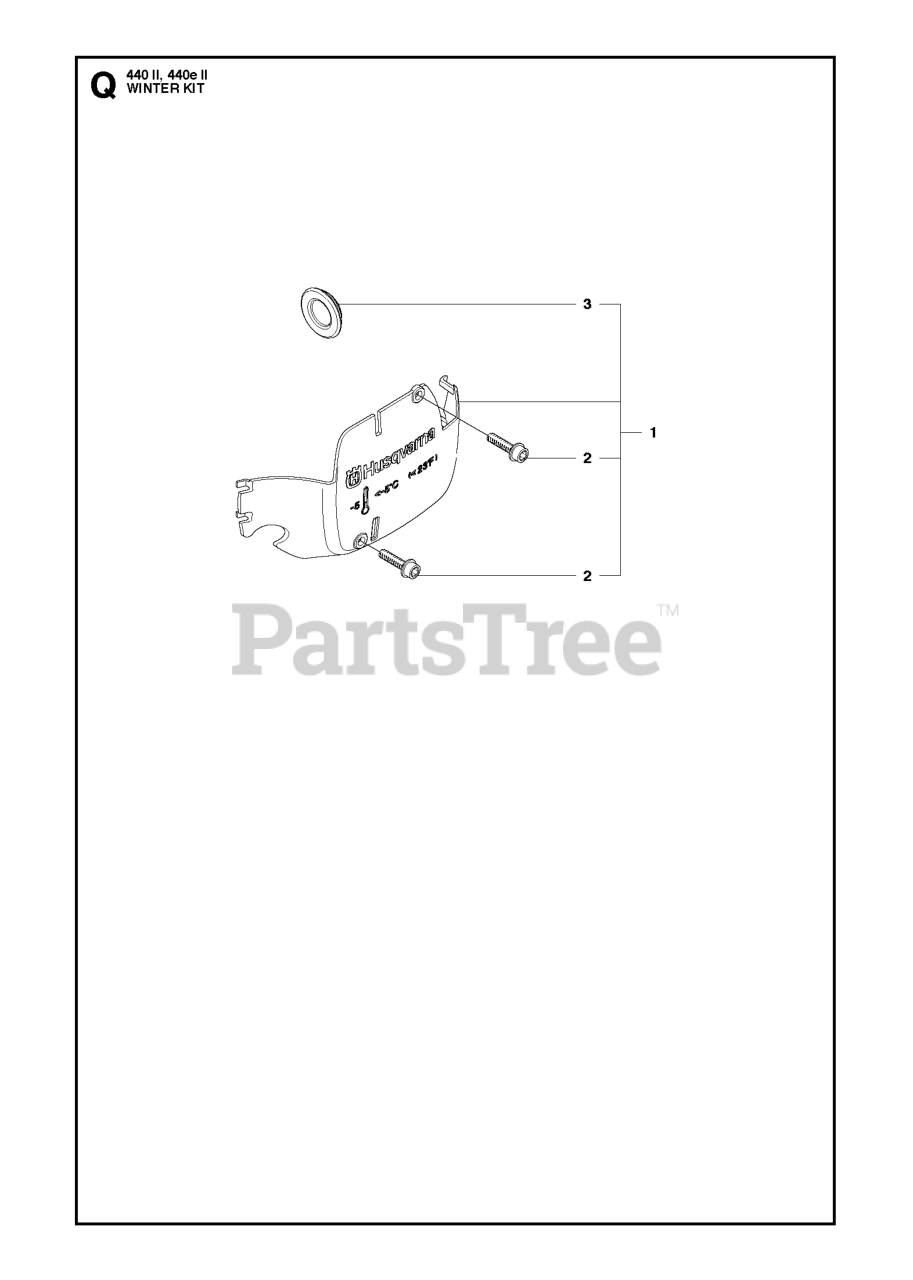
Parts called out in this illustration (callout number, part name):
1	WINTER KIT
2	SCREW
3	PLUG
